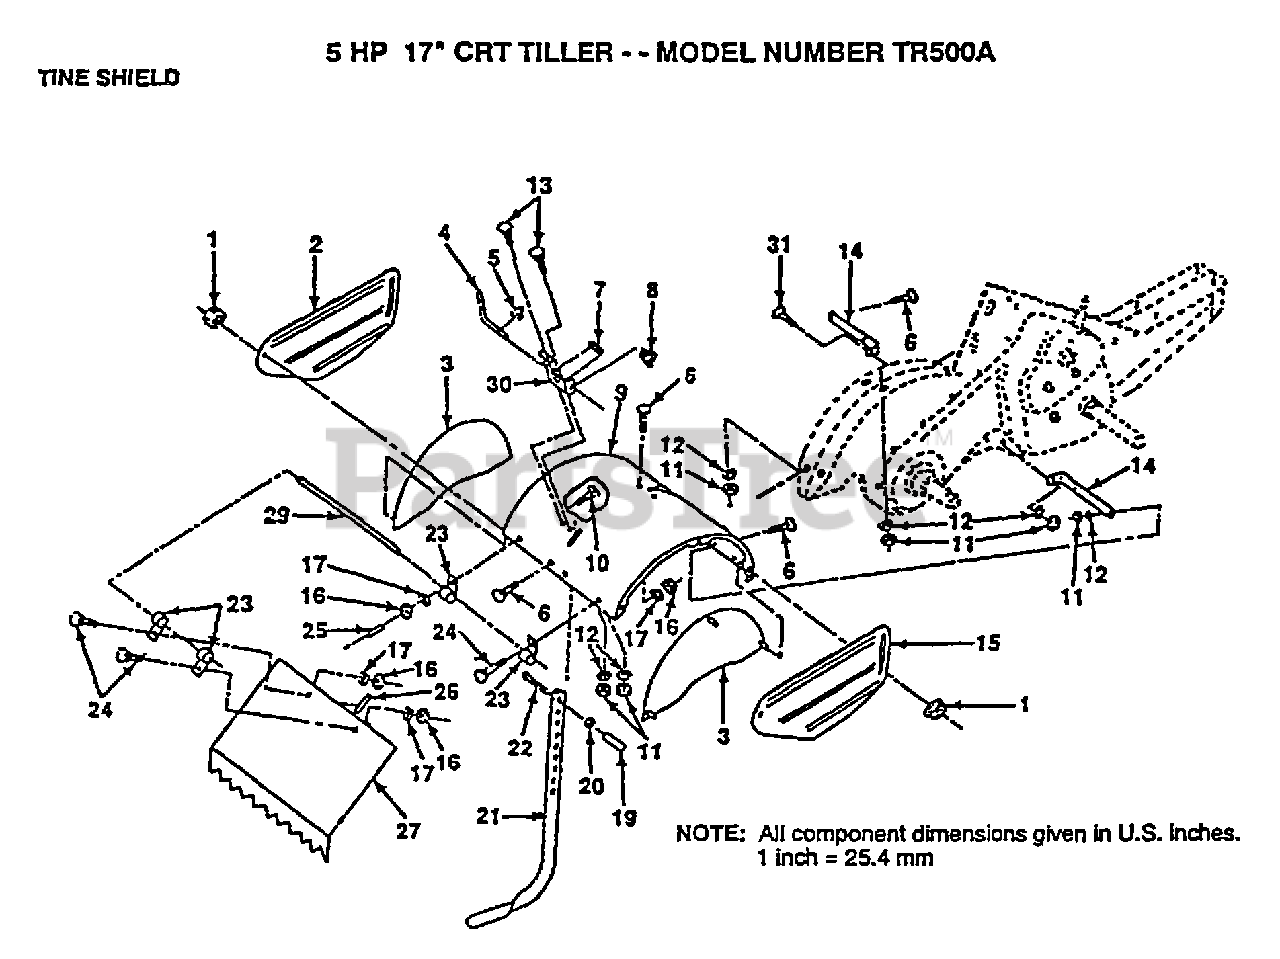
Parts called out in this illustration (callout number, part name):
1	NUT
2	SHIELD.SD.OUT.LH
4	STAKE PIN TI
5	KLIP RING TI
6	BOLT
7	SPRING TI
8	SPRING CRT
9	SHLD TINE
10	BOLT
11	NUT.HEX.5/16-18
12	LOCKWASHER
13	BOLT CRT
14	BRKT SHIELD TINE
15	SHIELD.SD.OUT.RH
17	LOCKWASHER
19	GRIP CRT
20	NUT.HEX.3/8-16UNC
22	BOLT
23	HINGE CRT
24	BOLT
25	VINYL CAP TI
26	PAD IDLER TI
29	PIN HINGE
30	LATCH BRACKET TI
31	BOLT
